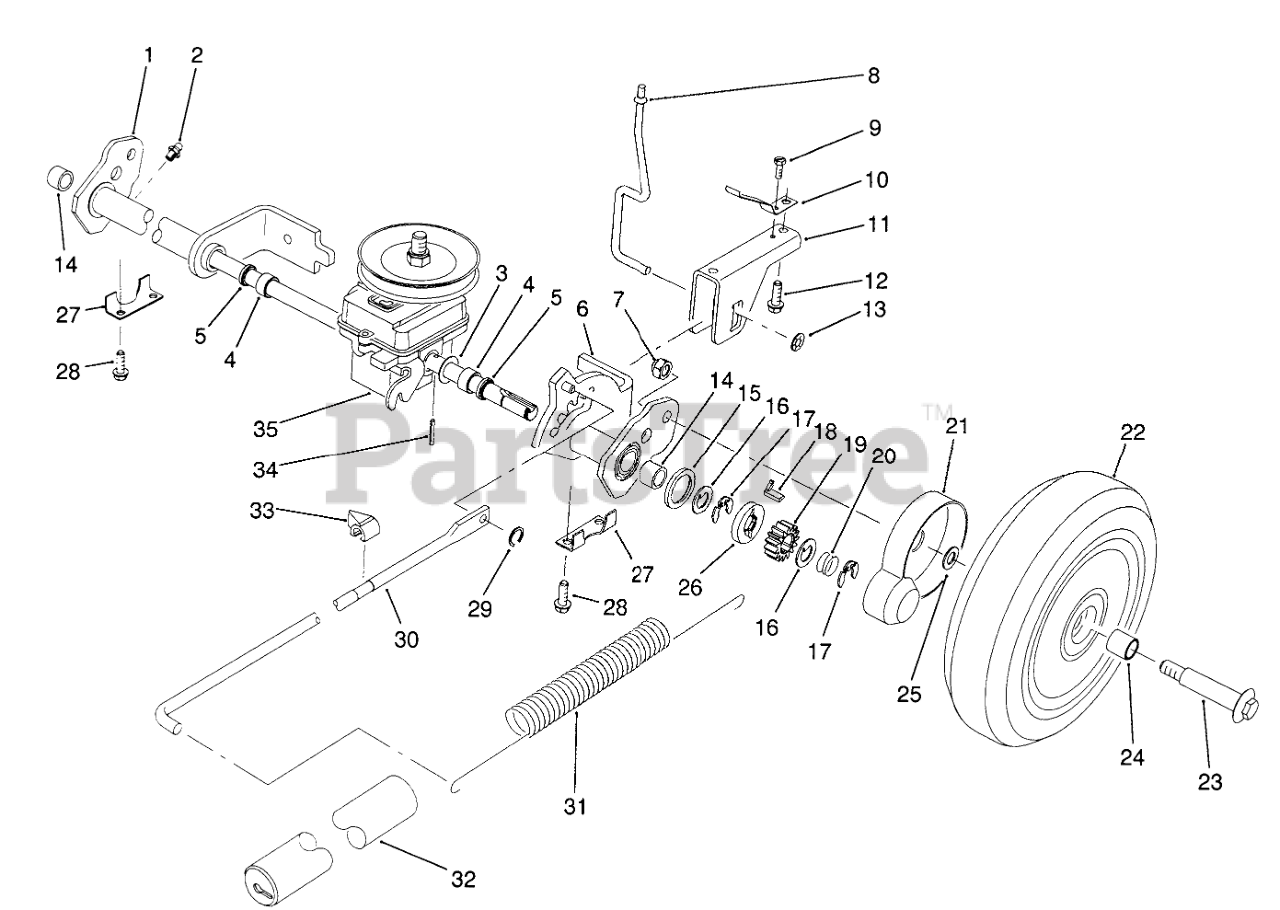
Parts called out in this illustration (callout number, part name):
1	Rear Pivot Assembly R.H. (Incl. Ref. #2, 4, 5 & 14)
2	FITTING-GREASE
3	WASHER-PLAIN
4	BUSHING
5	SEAL-OIL
6	Rear Pivot Assembly L.H. (Incl. Ref. #2, 4, 5 & 14)
7	Nut
8	TRIGGER ROD
9	SCREW 8 - 32 X 250
10	SPRING - TRIGGER RET
11	SADDLE - HOC
12	SCREW
13	PUSHNUT
14	BEARING-ROLLER
15	RING-FRICTION
16	WASHER-THRUST, KEYED
17	RING-CLIP, LOCKING
18	KEY-ROCKING, LH
19	GEAR-PINION
20	SPRING-COMPRESSION
21	COVER-WHEEL
22	Wheel, Tire & Gear Assy. (Incl. Ref. #24)
23	BOLT-WHEEL
24	BUSHING
25	SPACER-COVER, WHEEL
26	WASHER-CLUTCH
27	REAR SECURING PLATE
28	SCREW-HWHTF
29	GRIP RING
30	LINK ROD
31	SPRING-COUNTERBALANCE
32	COVER-SPRING
33	INDICATOR-HEIGHT OF CUT
34	COIL PIN
35	Gearbox Assembly
